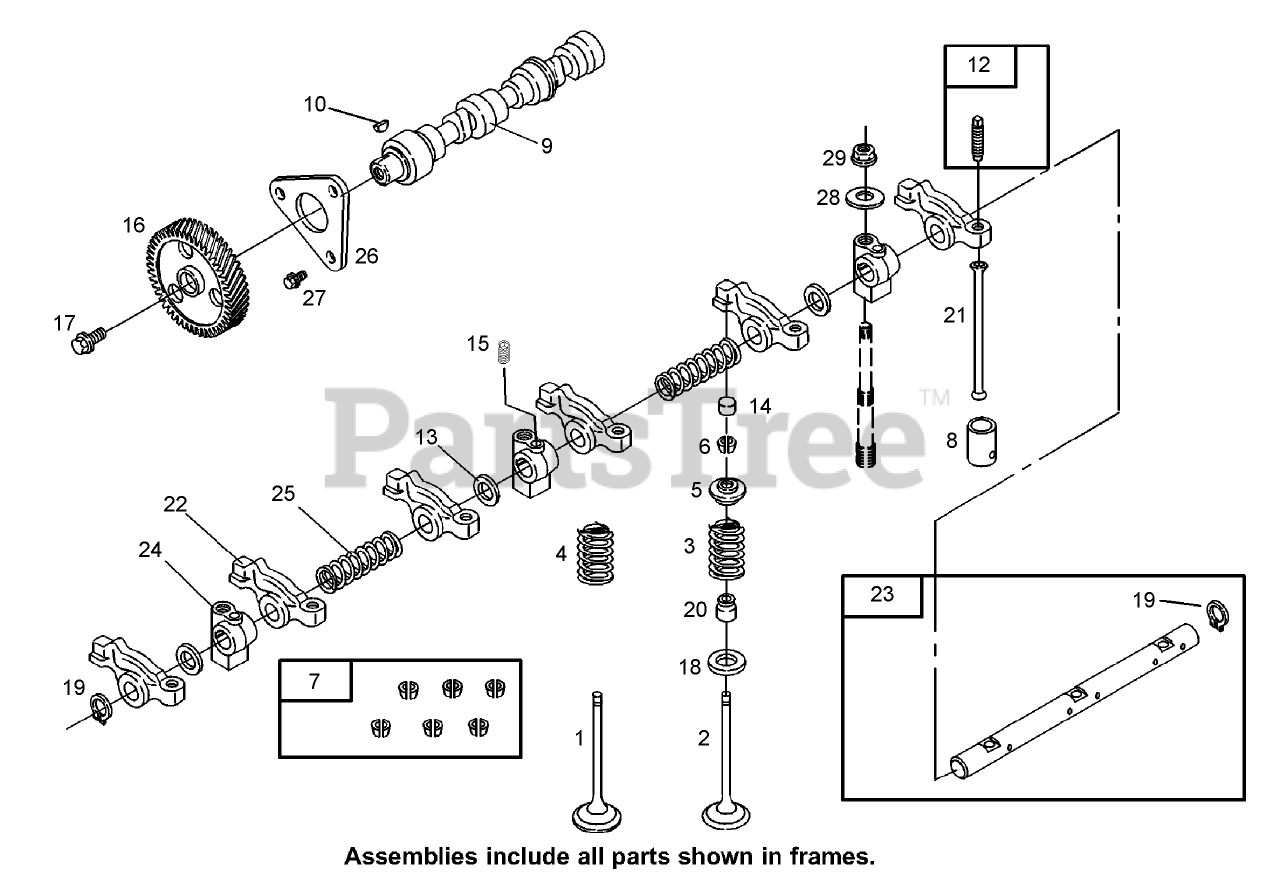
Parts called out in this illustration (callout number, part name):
1	VALVE-EXHAUST
2	VALVE-INTAKE
3	SPRING-VALVE
4	SPRING-VALVE
5	RETAINER-VALVE
6	KEEPER-VALVE (SET)
7	KEEPER-VALVE (SET OF 6)
8	TAPPET-VALVE
9	SHAFT-CAM
10	Key-Timing
12	ADJUSTER-ARM, ROCKER
13	WASHER-SPACER
14	CAP-VALVE
15	SCREW-METRIC
16	GEAR-CAM
17	SCREW-METRIC
18	SEAT-SPRING, VALVE
19	RETAINER
20	SEAL-VALVE
21	ROD-PUSH
22	ARM-ROCKER
23	SHAFT-ARM, ROCKER
24	SUPPORT-ARM, ROCKER
25	SPRING-SHAFT, ROCKER
26	RETAINER-CAMSHAFT
27	SCREW-HEX
28	WASHER-FLAT
29	NUT-HEX, METRIC
